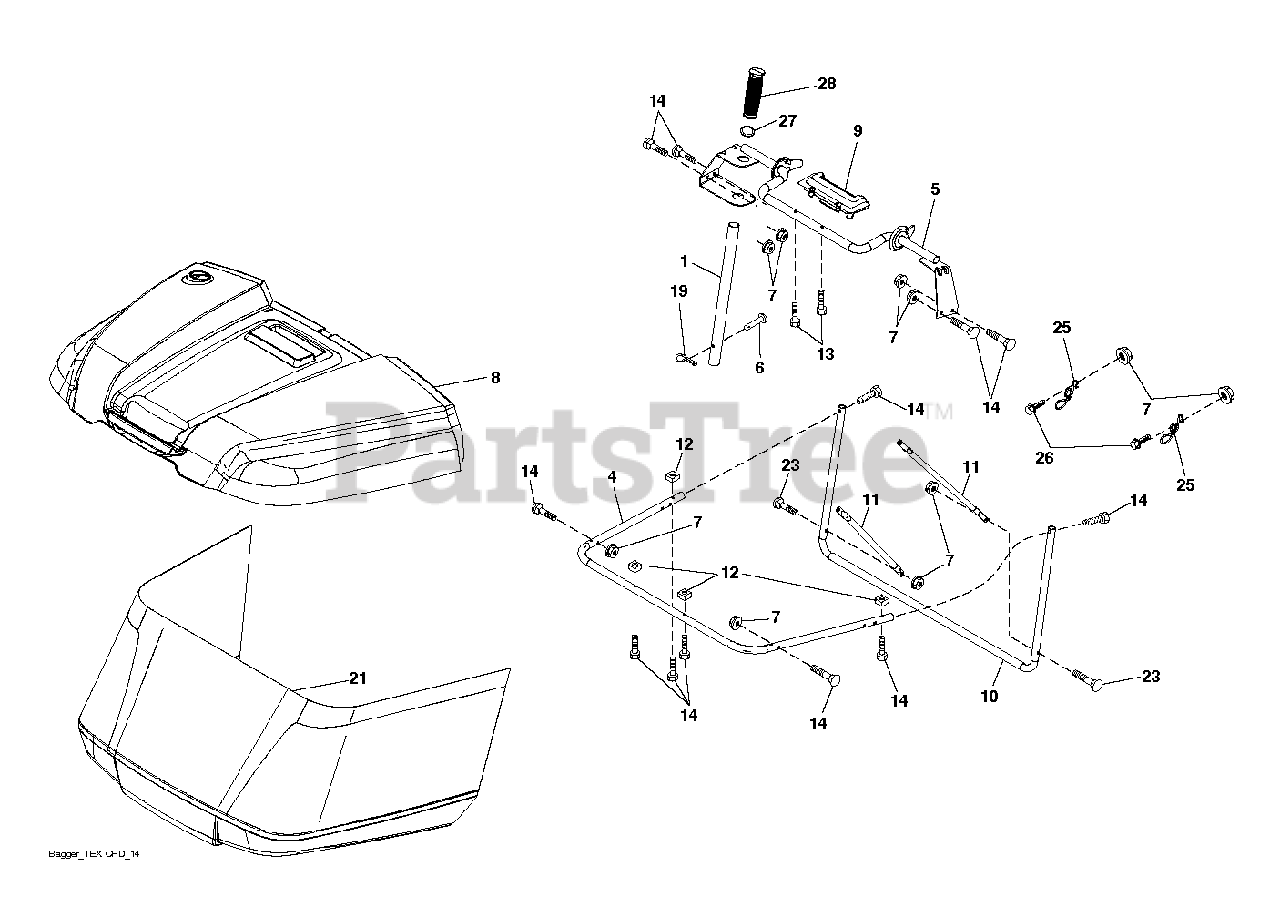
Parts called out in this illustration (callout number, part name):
1	TUBE.PNT.HDL.BAGGER.
6	RIVET,DRILLED
7	NUT T
19	PIN.COTTER.5/16.BOW TI
26	SCREW HEX CRT
28	GRIP.HANDLE.BLACK
